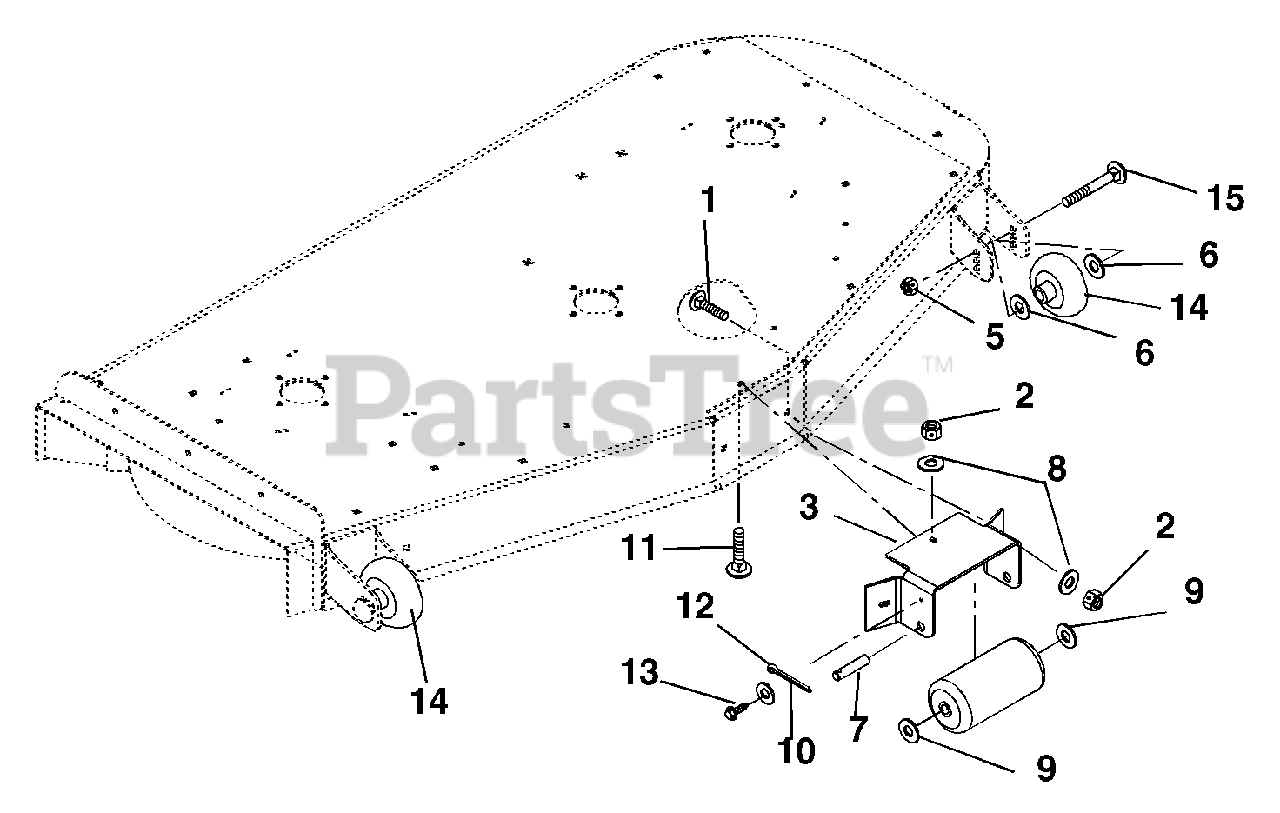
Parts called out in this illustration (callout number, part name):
1	Bolt-Round Head Square Neck .38-16 x 1.00 Grade 5)
2	Nut-Locking-Nylon .38-16
3	Bracket, Anti-Scalp Roller
5	Nut-Locking-Nylon .50-13
6	Washer-Flat-Steel .531 x 1.06 x .095
8	Washer-Flat-Steel .406 x .812 x .065
9	Washer-Flat-Steel .656 x 1.31 x .095
10	Washer-Flat-Steel .281 x .62 x .065
11	Bolt-Round Head Square Neck .38-16 x 1.25 Grade 5
12	Pin-Cotter .25 x 2.00
13	Screw-Self Tapping .25-20 x .50 x Hex Washer Head
14	Wheel, 3 x 5
15	Bolt-Round Head Square Neck .50-13 x 5.00 Grade 2
